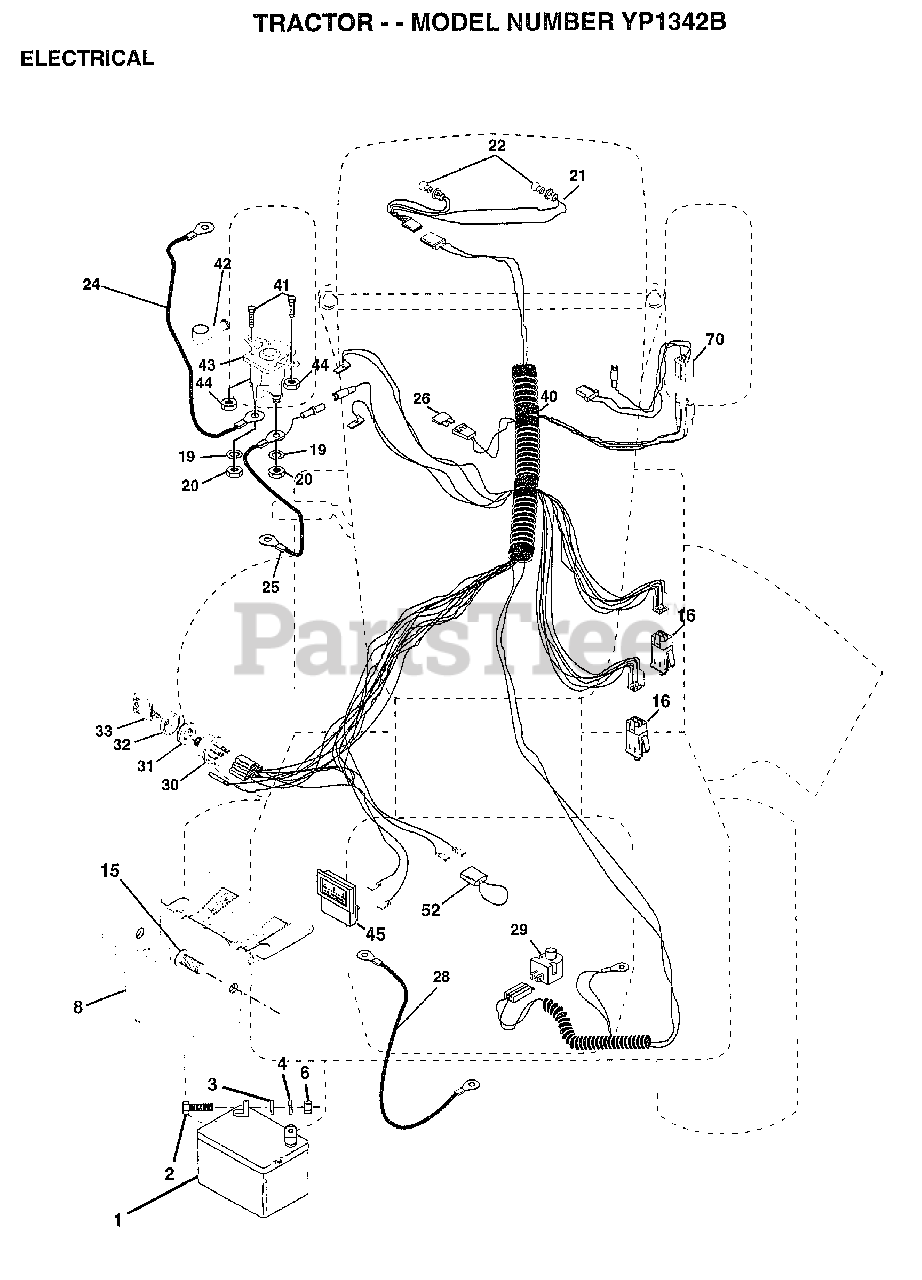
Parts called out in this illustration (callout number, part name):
2	BOLT LT
3	WASHER
4	LOCKWASHER
8	"CASE,BATTERY.MECH"
15	FASTNER.SNAP-IN
16	SWITCH INTERLOCK
20	NUT
21	"HARNESS,LIGHT SOC"
22	HEADLAMP BULB
24	"CABLE T, BATTERY"
25	CABLE.BTRY.6GA.RD
26	FUSE HYT
28	CABLE T
29	SWITCH SEAT
30	SWITCH IGN 4POS
31	NUT IGNITION
32	COVER KEY SWITCH
33	KEY
40	HARNESS-IGNITION
41	BOLT HXHD FIN
44	NUT HXKEP 1/4X20
52	PROTECTION LOOP
70	HARNESS ENG DUAL
